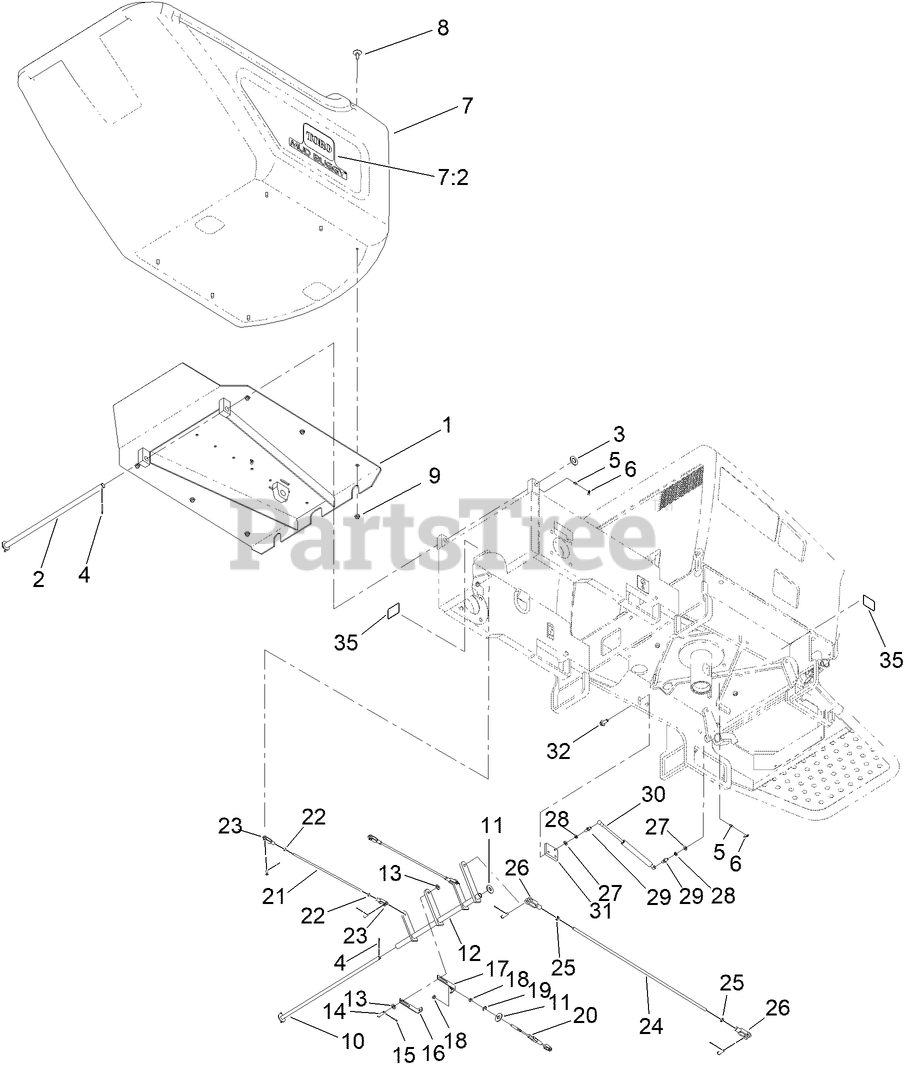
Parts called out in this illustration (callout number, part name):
1	HOPPER BASE ASM [BLACK]
2	SHAFT-PIVOT
3	WASHER-FLAT
4	PIN-COTTER
5	FITTING-GREASE
6	CAP-PLUG
7	HOPPER-MORTAR, ASM
7:2	DECAL-TUB, ULTRA BUGGY
8	BOLT-ELEVATOR
9	NUT-HF, NI
10	SHAFT-PIVOT, LEVER (BRAKE)
11	WASHER-FLAT
12	LEVER-BRAKE
13	WASHER-FLAT
14	PIN-CLEVIS
15	PIN-COTTER
16	CLEVIS-HALF
17	CLEVIS-HALF (NOTCHED)
18	NUT-JAM
19	RING-RETAINING, EXTERNAL
20	CABLE-BRAKE, BUGGY
21	ROD-BRAKE, FRONT
22	NUT-HEX
24	ROD-BRAKE
25	NUT-HJ
26	YOKE-LINKAGE, BRAKE
27	WASHER-PLAIN
28	WASHER-LOCK
29	STUD-BALL
30	SPRING-GAS
31	PLATE-PIVOT, SPRING (GAS)
32	SCREW-HHF
35	DECAL-TIE DOWN
